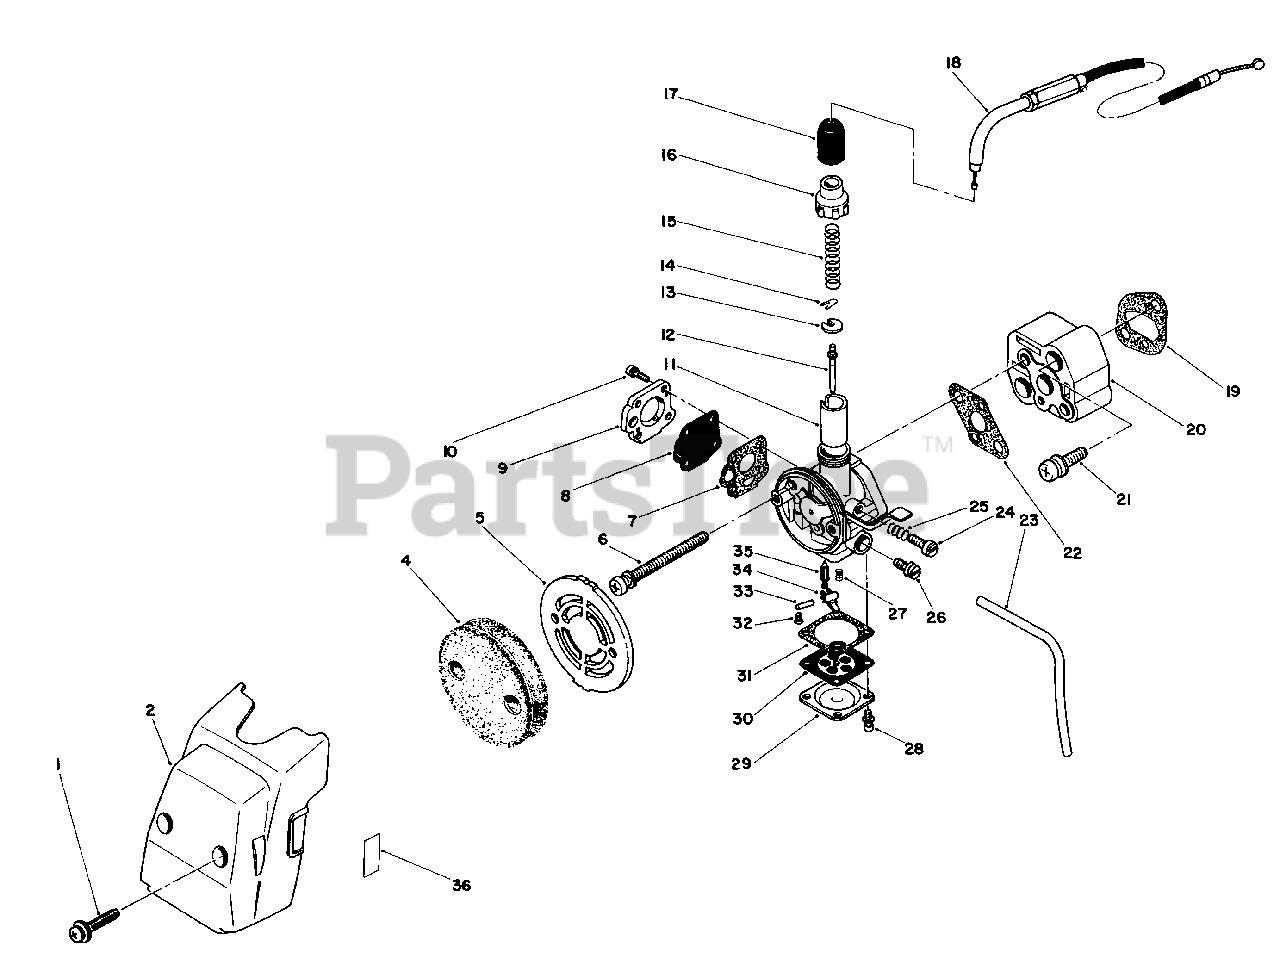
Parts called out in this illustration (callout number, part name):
1	Screw & Washer
2	Case, Cleaner
4	Element
6	Screw & Washer
7	Gasket, Pump Cover
8	Diaphragm, Pump
9	Pump Cover Assembly
10	Screw & Washer
11	Valve, Throttle
12	Jet Needle Assembly
13	Retainer, Spring
14	Clip, Needle
15	Spring-Throttle
16	Cap, Mixing Chamber
17	Cap, Rubber
18	Cable, Throttle
19	Gasket, Insulator
20	Insulator
21	Screw & Washer
22	Gasket, Carburetor
23	Tube, Fuel
24	Screw, Adjusting
25	Spring, Adjusting Screw
26	Main Jet Needle Assembly
27	Spring, Inlet Valve
28	Screw & Washer
29	Cover, Main Diaphragm
30	Main Diaphragm Assembly
31	Gasket, Main Diaphragm
32	Setscrew, Float Pin
33	Pin, Float
34	Arm, Float
35	Valve, Float
36	Label, Choke
